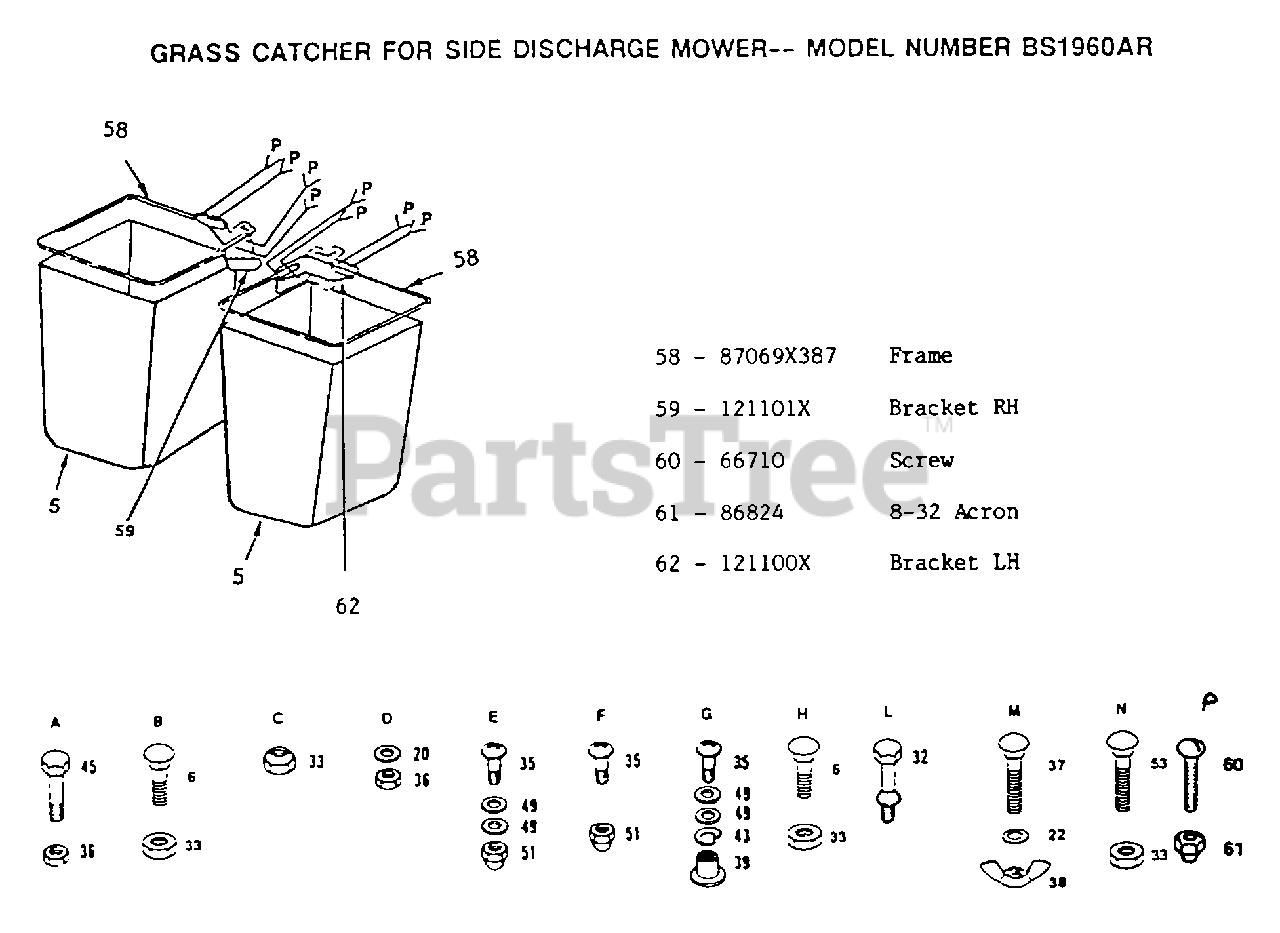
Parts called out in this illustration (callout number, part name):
5	GRASS BAG RB
6	BOLT
20	WASHER
32	LATCH RB
35	TRUSS HEAD MACHINE SCREW
37	BOLT
39	WELDNUT
43	LOCKWASHER
49	WASHER
53	BOLT CRT
59	BRACKET.FRAME
60	PAN HEAD SCREW
61	NUT ACORN RB
62	BRACKET FRAME
